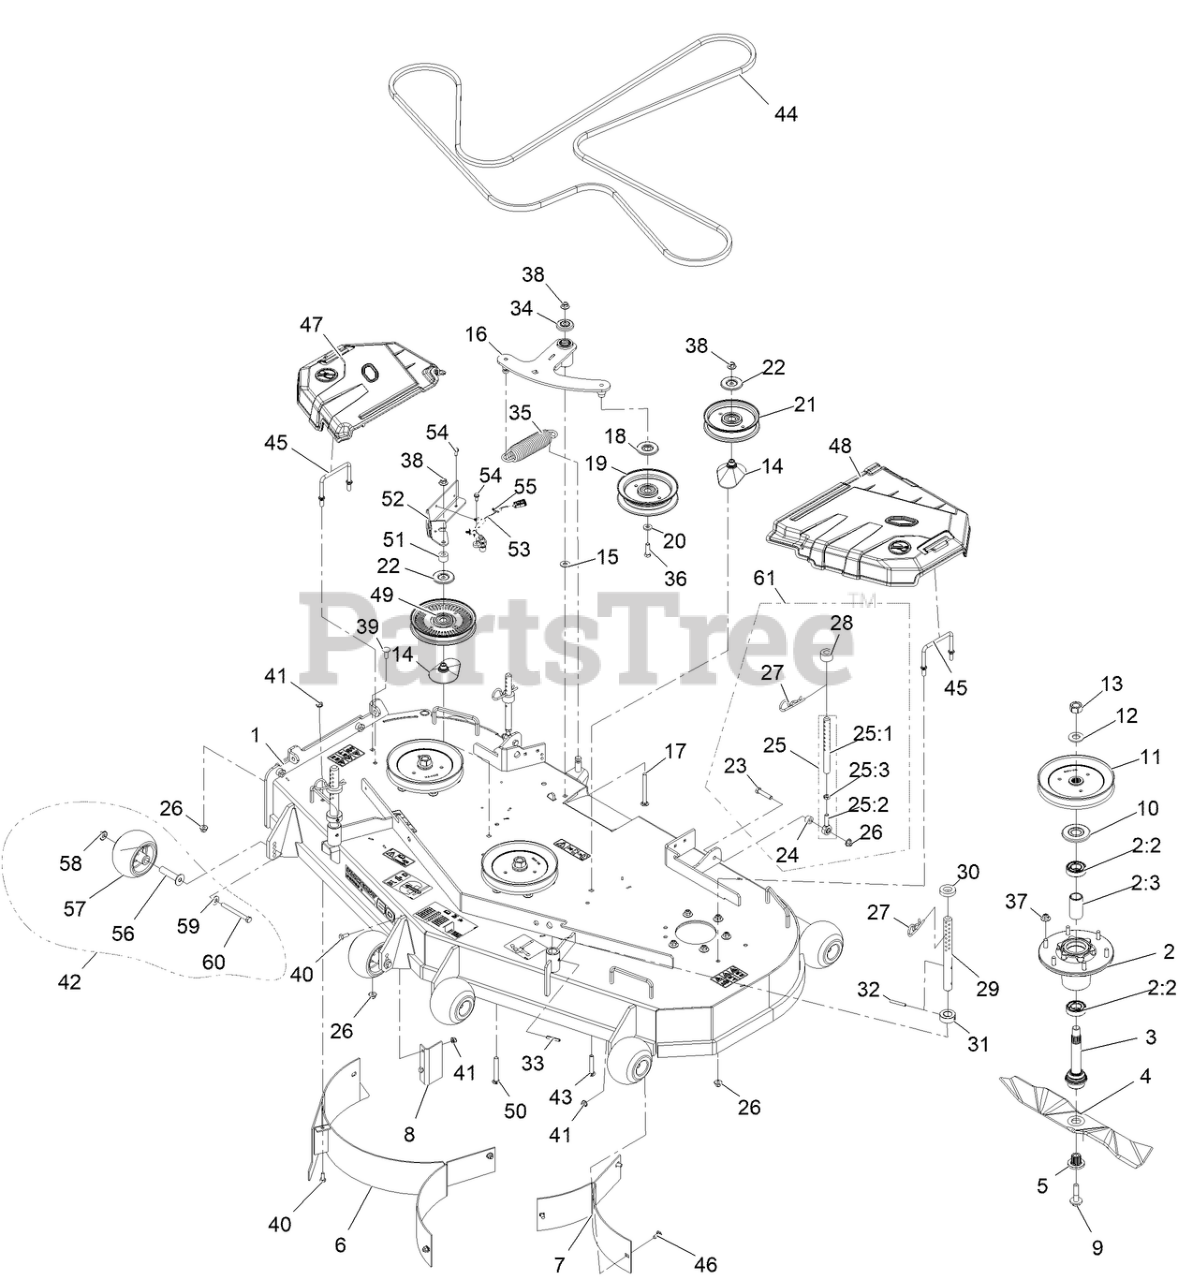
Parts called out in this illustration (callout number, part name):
1	ASM, DECK W/ DECALS, 60
2	ASM-CUTTER HSG WITH BEARINGS
2:2	BEARING-BALL
2:3	SPACER-BEARING
3	ASM-SPINDLE AND SEAL
4	Blade-Extreme 2, 20.50"
5	BUSHING,SPLINED
6	BAFFLE WLD RH MULCH
7	BAFFLE WLD LH MULCH
8	XREF 1-633956-03 (EXMARK)
9	SCREW,SEMS 1/2-20 X 2.19
10	GUARD,BEARING TOP .989
11	SHEAVE,BLADE DRIVE 7.25
13	NUT-HEX
14	SPACER-PULLEY
15	WASHER-FLAT
16	ASM, DECK IDLER
17	SCREW-CARR
18	SHIELD-GUARD, DUST
19	IDLER-PULLEY, FLAT
21	Pulley-Idler, Flat
22	SHIELD-DUST
23	SCREW-HH
25	ASM, SUPPORT LINK
25:1	PIN-DECK SUPPORT
25:2	BALLJOINT
25:3	NUT-HJ
26	NUT-HF, NI
27	PIN-CUT HEIGHT
29	PIN-DECK SUPPORT
30	SPACER-DECK SUPPORT
31	COLLAR, DECK HEIGHT PIN
32	PIN-ROLL
34	GUARD-TOP
35	SPRING-EXTENSION
36	SCREW-HH
37	Nut-Nyloc 3/8-16 Flg
39	SCREW-CARR
40	SCREW-HH
41	NUT-HF, NI
42	KIT, ANTI-SCALP ROLLER
43	BOLT-CARR, SHORT NECK
45	WIREFORM-COVER
46	BOLT-CARR
47	SHIELD, RT
48	SHIELD, LT
49	ASM, IDLER WITH TARGET
50	SCREW-CARR
52	BRACKET-SENSOR, BLADE
53	SENSOR-SPEED
54	SCREW-HWH
55	CLIP-TIE, FIR TREE W/TIE, 5MM/.196"" HOLE
56	AXLE, ROLLER
57	ROLLER-SCALP, ANTI
58	Nut-Nyloc 3/8-16 Flg
59	WASHER-BELLEVILLE
60	SCREW-HH 3/8-16 X 3 3/4 GR 8
61	KIT,SUPPORT LINK W/PIN
